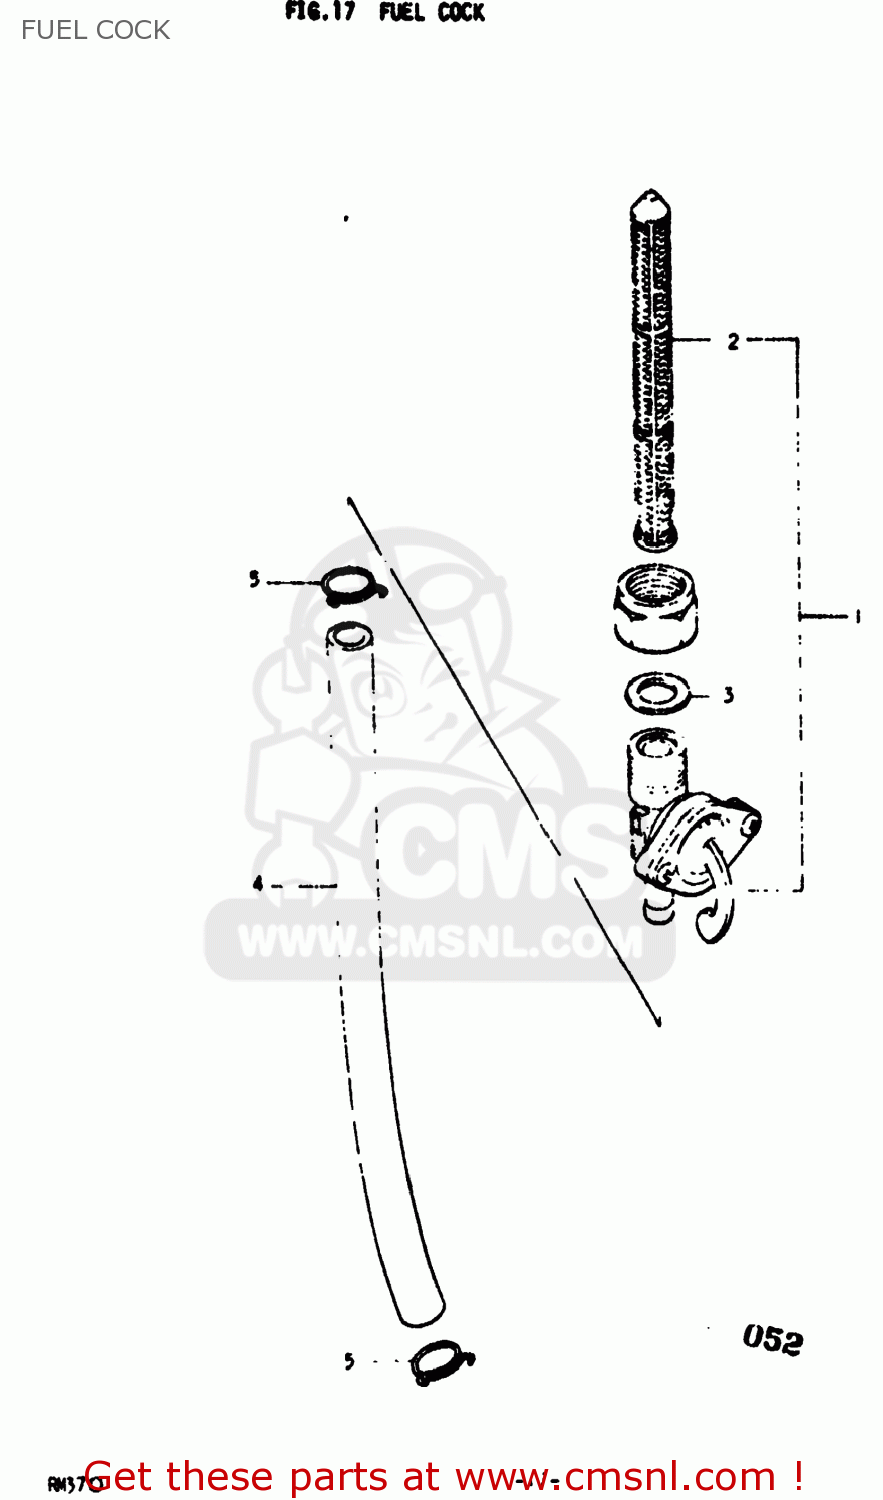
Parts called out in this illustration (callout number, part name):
1	COCK ASSY,FUEL
2	FILTER,FUEL
3	GASKET,FUEL COCK (NAS)
4	HOSE
5	CLIP
